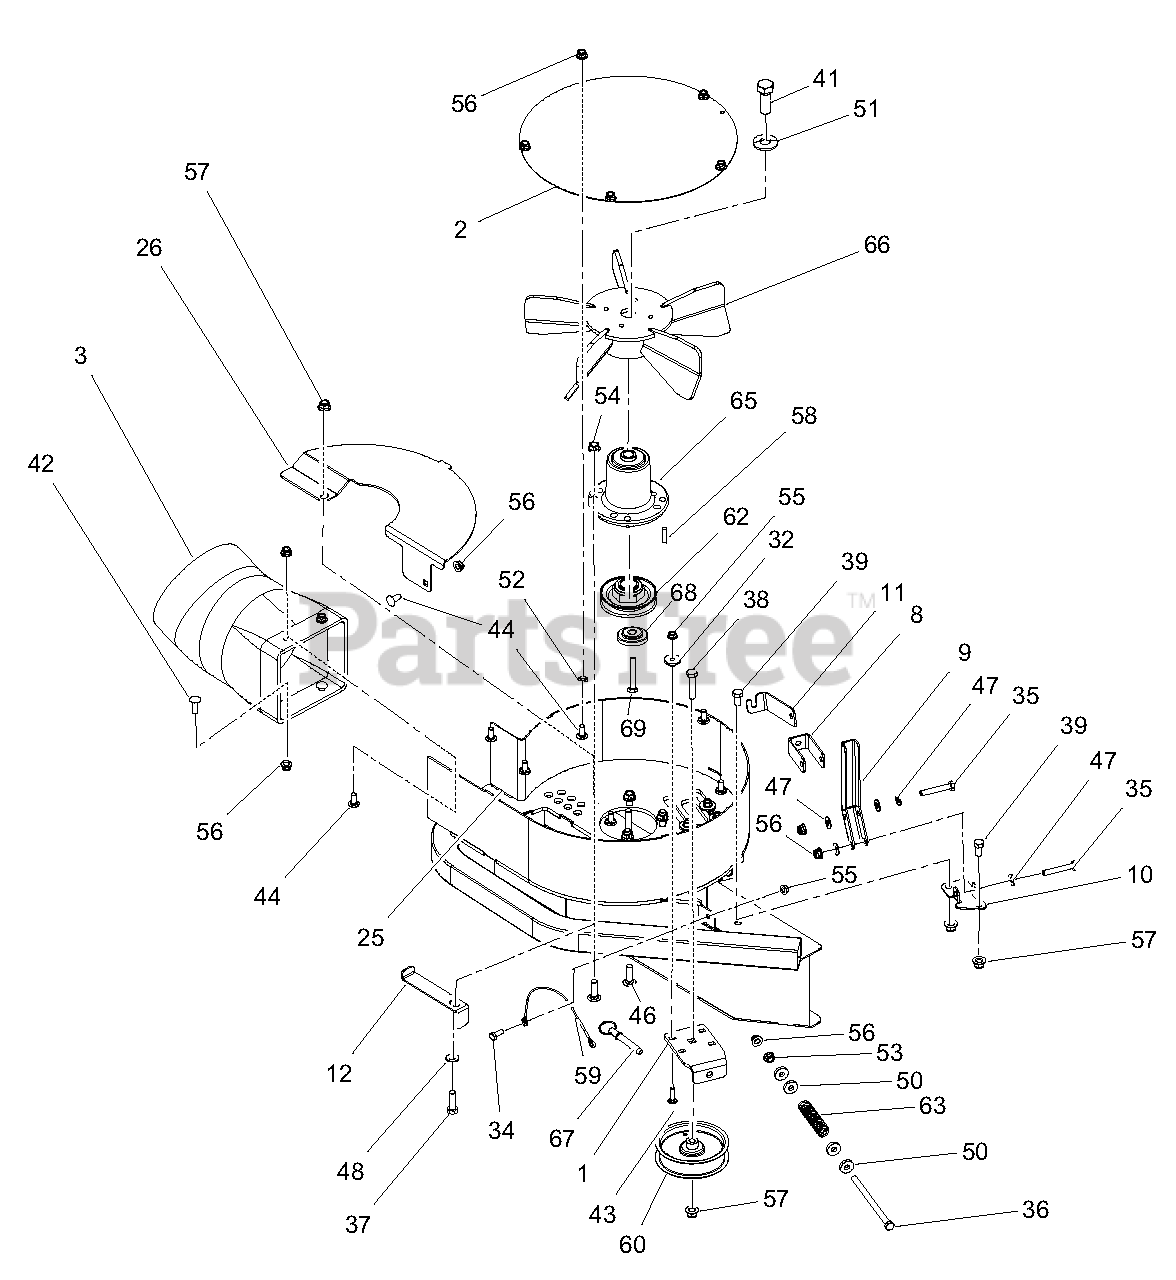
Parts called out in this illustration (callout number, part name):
1	BRKT, ADJUSTABLE IDLER
2	COVER, BLOWER -BLACK
3	ADAPTER, HOSE
8	LINK, IDLER RELEASE-BLACK
9	LEVER, IDLER RELEASE-BLACK
10	MOUNT, IDLER RELEASE LEVER-BLK
11	LOCK, IDLER RELEASE LEVER-BLACK
12	FINGER BELT-BLACK
25	WELDMENT, BAGGER BLOWER-RED
26	COVER, BOTTOM - BLK
32	BSHG, FLG .265 X .477 X .375 X 1.00
34	BLT-HEX .25-20 X .75
35	BLT-HEX .31-18 X 2.00
36	BLT-HEX .31-18 X 5.50
37	BLT-HEX .38-16 X 1.25
38	BLT-HEX .38-16 X 1.75
39	@BLT-HEX .38-16X.75 GR5 YWZC
41	BLT, HEX .62-18 X 1.75
42	BLT-RDHDSQSHNK .31-18 X 1.00
43	BLT-RDHDSQNK .25-20 X 1.00
44	BLT-RHDSSQNK .31-18 X .75
46	BLT-RDHDSQNK .38-16 X 1.25
47	WSHR-FL-NYL .375 X .75 X .060
48	WSHR-FL-STL.406 X .812 X .065
50	WSHR-FL-STL .328 X .87 X .179
51	WSHR, BLVL .63 X 1.625 X .14
52	NUT, PUSH .312
53	NUT-SPNLK-FLG .312-18
54	NUT, LK-CTR-FLG .38-16
55	NUT, LK-TOP-FLG .25-20
56	NUT-LK-NYL-FLG .31-18
57	NUT-LK-NYL-FLG .38-16
58	KEY SQUARE .25 X .25 X 1.00 RC 40 - 50
59	LANYARD, 12"
60	PULLEY, IDLER 4.00 X .375
62	PULLEY, 1" OD X 3.50" OD-LOW FILM
63	SPRG, COMPRESSION
65	SPINDLE BLOWER ASSEMBLY
66	WLDMT, IMPELLER FAN
67	PIN, SPRING BALL .375 OD X 1.50
68	RETAINER, SHEAVE
69	BLT-HEX .38-16 X 2.75
